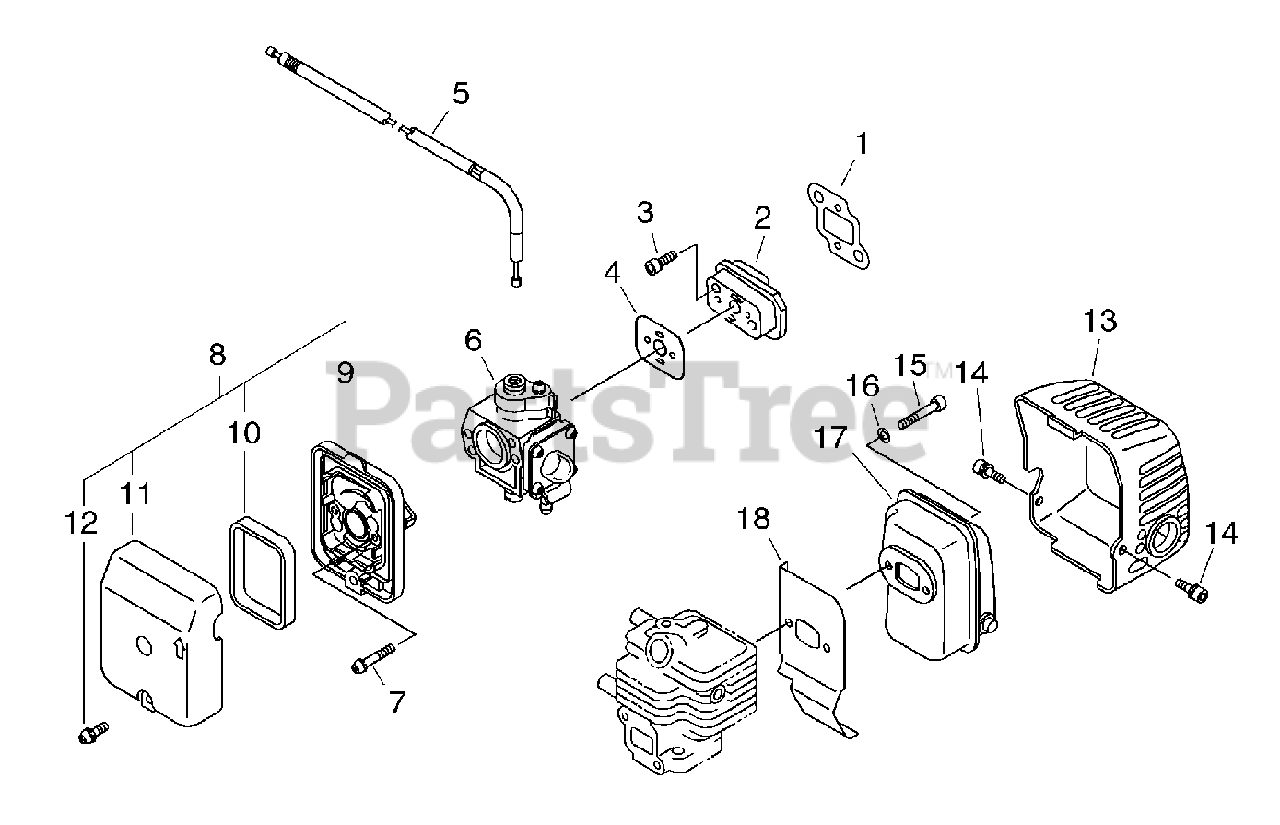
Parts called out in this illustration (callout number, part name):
1	GASKET, INTAKE
2	INSULATOR, INTAKE
3	BOLT 5×25
4	GASKET, INTAKE
5	CABLE, THROTTLE
6	CARBURETOR TK KR8PR-1B
7	SCREW 5×50
8	FILTER ASSY, AIR
9	CASE, AIR FILTER
10	FILTER, AIR #30
11	COVER, AIR FILTER
12	SCREW 5×16
13	COVER, MUFFLER
14	BOLT 5×8
15	BOLT 5×55
16	WASHER, FLAT 5.5×10×0.8
18	HEAT SHIELD, EXHAUST
